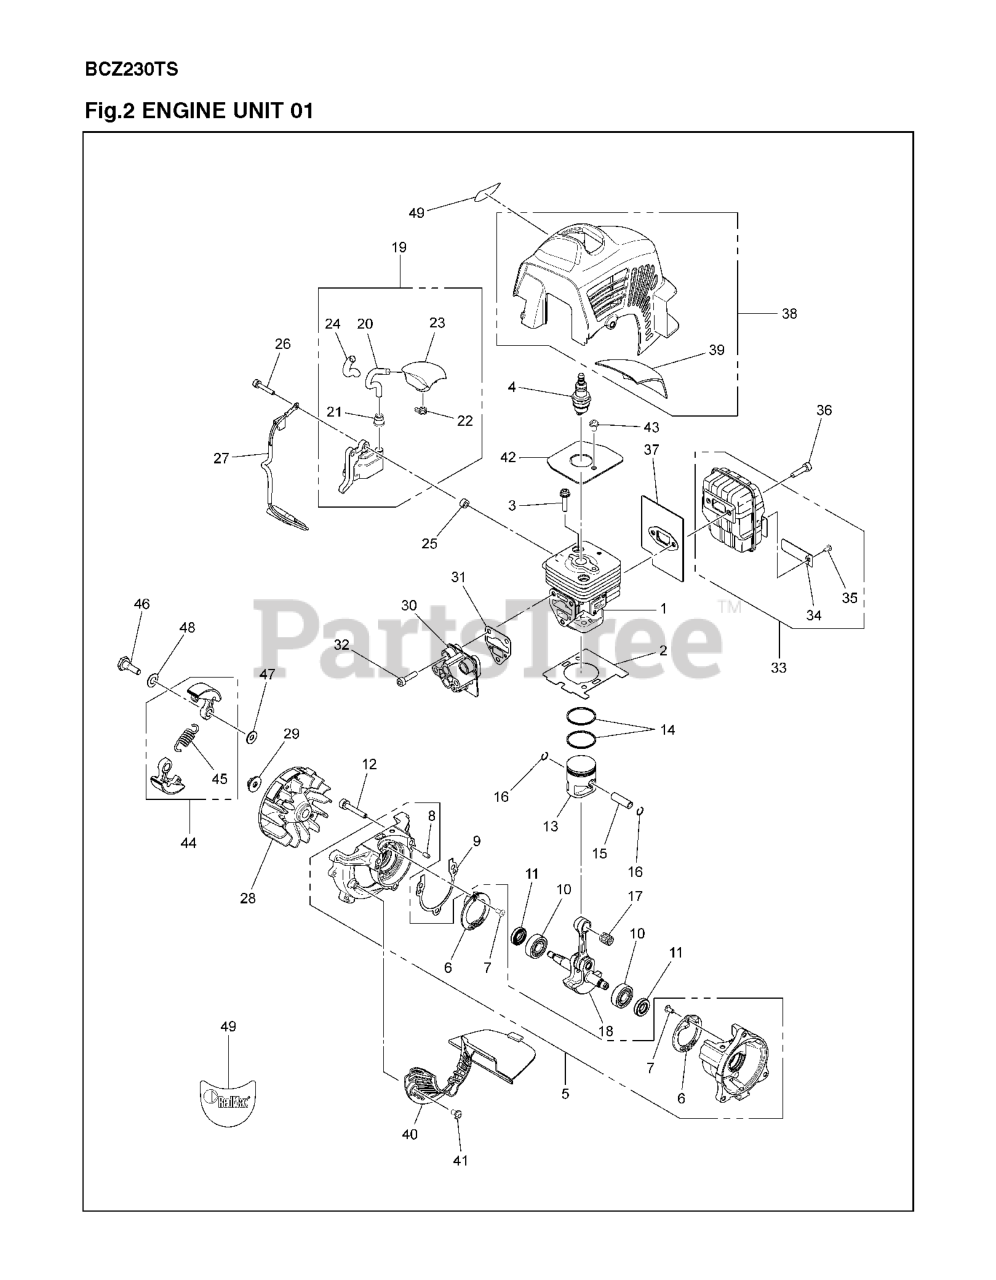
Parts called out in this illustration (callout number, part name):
1	CYLINDER COMP
2	GASKET BASE
3	BOLT
4	SPARK PLUG, BPMR8Y
5	CRANKCASE ASSY
6	COVER CASE
9	GASKET CASE
11	OIL SEAL 8488AA2000
14	RING PISTON
15	PIN.PISTON 8488B82600
18	CRANKSHAFT COMPLETE
19	IGNITION COIL ASSY
20	IGNITION CABLE
21	HUB CAP 848F6L71E0
23	SPARK PLUG CAP
24	TUBE (RPLS 263072210)
25	SPACER
26	BOLT M4 X 25
27	SHORT CIRCUIT CABLE
28	FLYWHEEL
30	INSULATOR
33	MUFFLER ASSY
34	SPARK ARRESTER
35	SCREW CRPANT TYPE F ST4.2X9.5
37	GASKET MUFFLER
38	CYLINDER COVER COMPLETE
39	SHEET HEAT INSULATION TRZ230/B
40	PLATE MUFFLER
42	PLATE CYLINDER
44	CLUTCH ASSY
45	CLUTCH SPRING
49	DECAL BRAND
